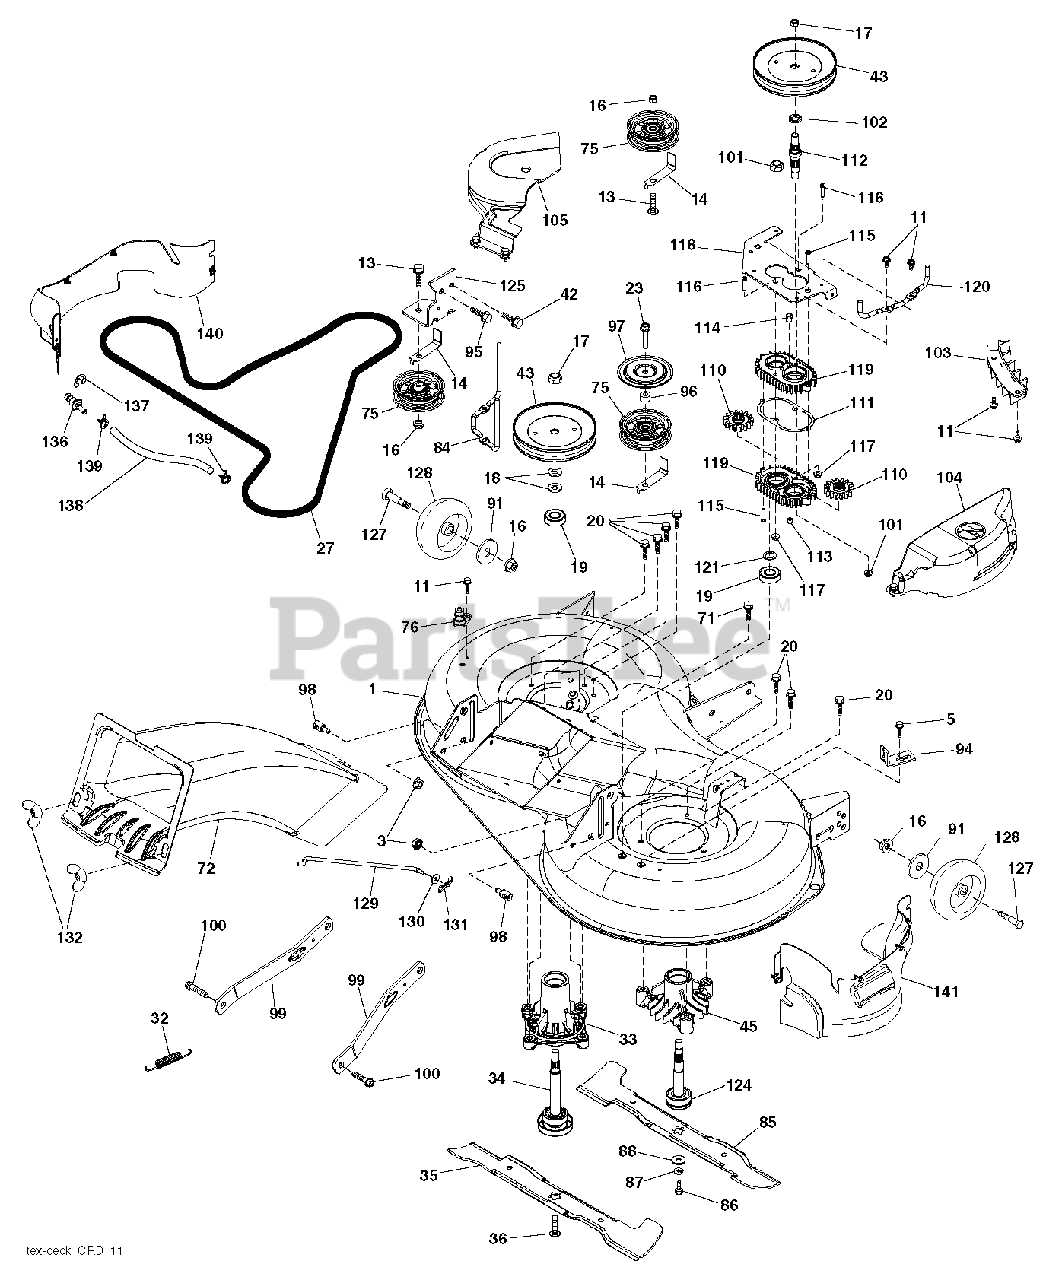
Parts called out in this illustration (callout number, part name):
3	NUT LOCK HEX FLANGE 5/16-18
5	BOLT.5/16HEX.WHS.HD
11	SCREW.1/4-20X5/8
13	BOLT.3/8-16X1.50
14	KEEPER, BELT IDLER
16	NUT LOCK FLG 3/8-16 UNC
17	NUT.FLANGE.LOCK.TOP
18	WASHER.SPACER.MANDREL
20	SCREW, WASHER HEAD
23	SCREW LT
27	BELT 97CM ELECTRIC
32	SPRING 107CM & 97CM ELECTRIC D
33	HOUSING.MANDREL.4PT.
34	SHAFT.ASM.MDRL.N/GREASE.38
35	BLADE.3N1.LH.CRD.97
36	BOLT.WASHER.ASM.7/16-2
42	SCREW
43	PULLEY.MANDREL.5.0.PD.38"
45	HOUSING.MANDREL.44/46" VENT
71	SCREW 3/8-16X1/2
72	CHUTE REAR CRD UPPER CHUTE TEX
75	FLAT IDLER PULLEY
76	1/2" BARB.DECK.WASHOUT.PORT
84	BELT KEEPER.MANDREL.38"COATED
85	BLADE.3N1.RH.CRD.97
86	BOLT.3/8-24X1.25GR8. LHTHRD
87	LOCKWASHER
88	WASHER.BLADE
91	WASHER
94	BRKT.CLUTCH.CABLE
95	SCREW, 3/8-16X3/4
96	SPACER
97	PROTECTOR
98	STUD.FASTNER.W/ANTI-ROTATE
99	ARM.SUSPENSION.MOWER.R
100	BOLT.SHOULDER
101	NUT.CROWNLOCK.9/16 -18.UNC
102	SPACER BEARING
103	GUARD GUARD FRONT VENT
110	GEAR GEAR OUTPUT
111	GASKET GASKET GEARCASE
112	SHAFT SHAFT. CRD GEARCASE ADAP
113	PLUG PLUG OIL
114	VALVE VALVE RELIEF
115	SCREW
116	BOLT.CARIGE.SS.1/4-20X1.75GR5
117	NUT T
118	ARM ARM CLUTCHING
119	GEARCASE GEARCASE SUBASM
120	BRACKET KEEPER BELT RH
121	WASHER WASHER
124	MANDREL SHAFT NON/GREASE
125	BRACKET BRACKET IDLER CHASSES
127	BOLT.SHOULDER.3/8-16X3-5/8.
128	WHEEL. GUAGE RALLY
129	ROD.ANTI.SWAY.48/54"K4
130	WASHER
131	PIN.COTTER.5/16.BOW TI
132	KNOB.HANDLE.3/8.TRI-POINT.BLAC
136	PLUG WASHOUT PORT HOOKUP
138	HOSE.3/8ID.BULK.12"
139	HOSE.3/8.CLAMP (2 2)
140	GUARD
141	GUARD SUBASM.TEX CRD 97CM RH F
